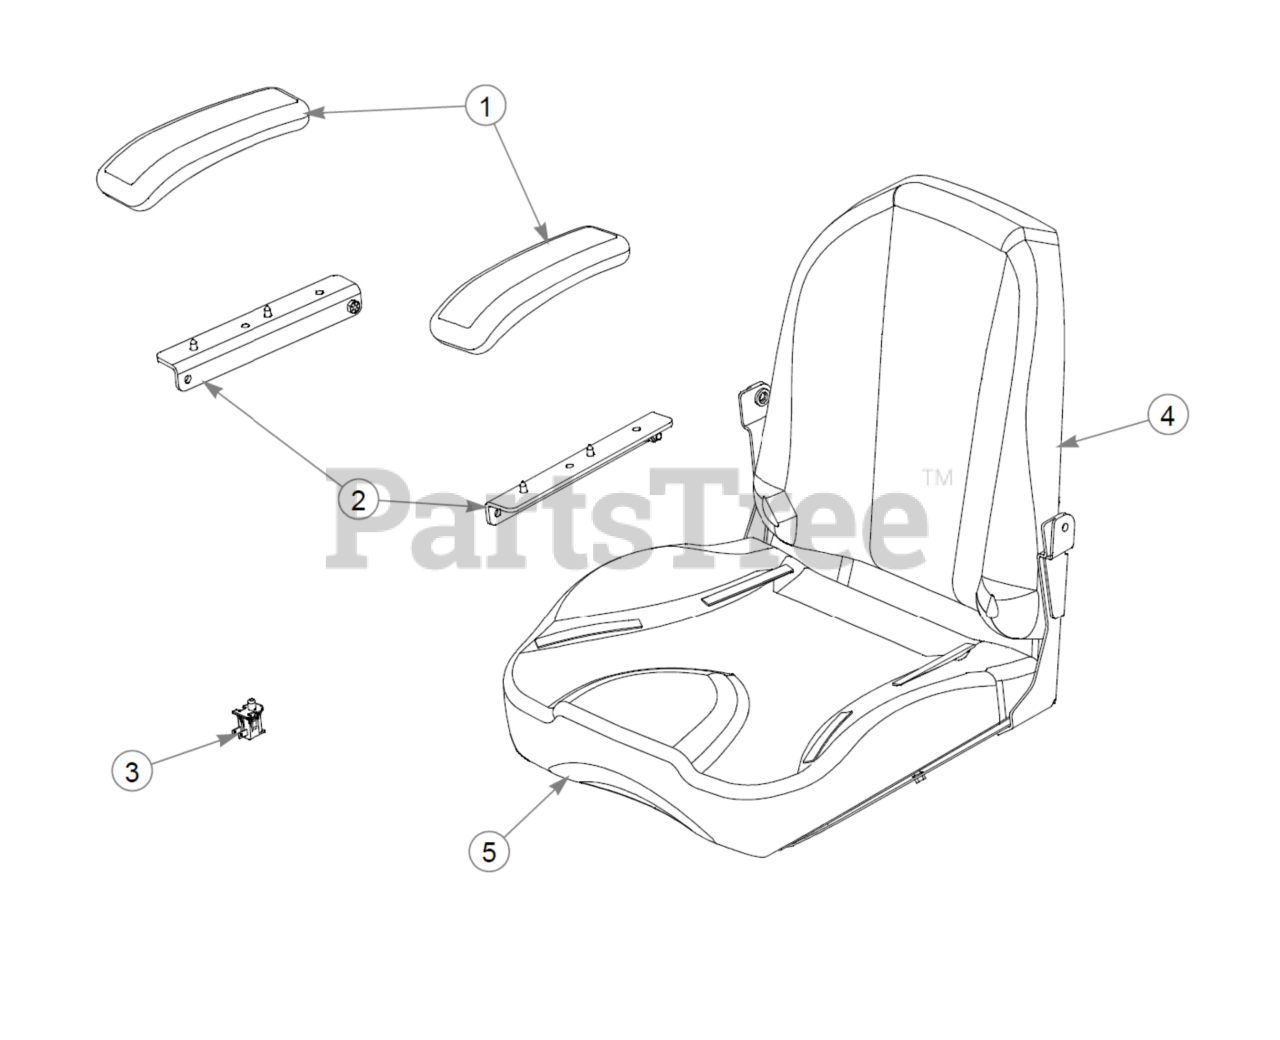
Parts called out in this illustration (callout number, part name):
1	SVC, ARM PAD
2	SVC, ARMEST SET
3	SVC, OPS
4	SVC, BACK CUSHION
5	SVC, SEAT CUSHION
